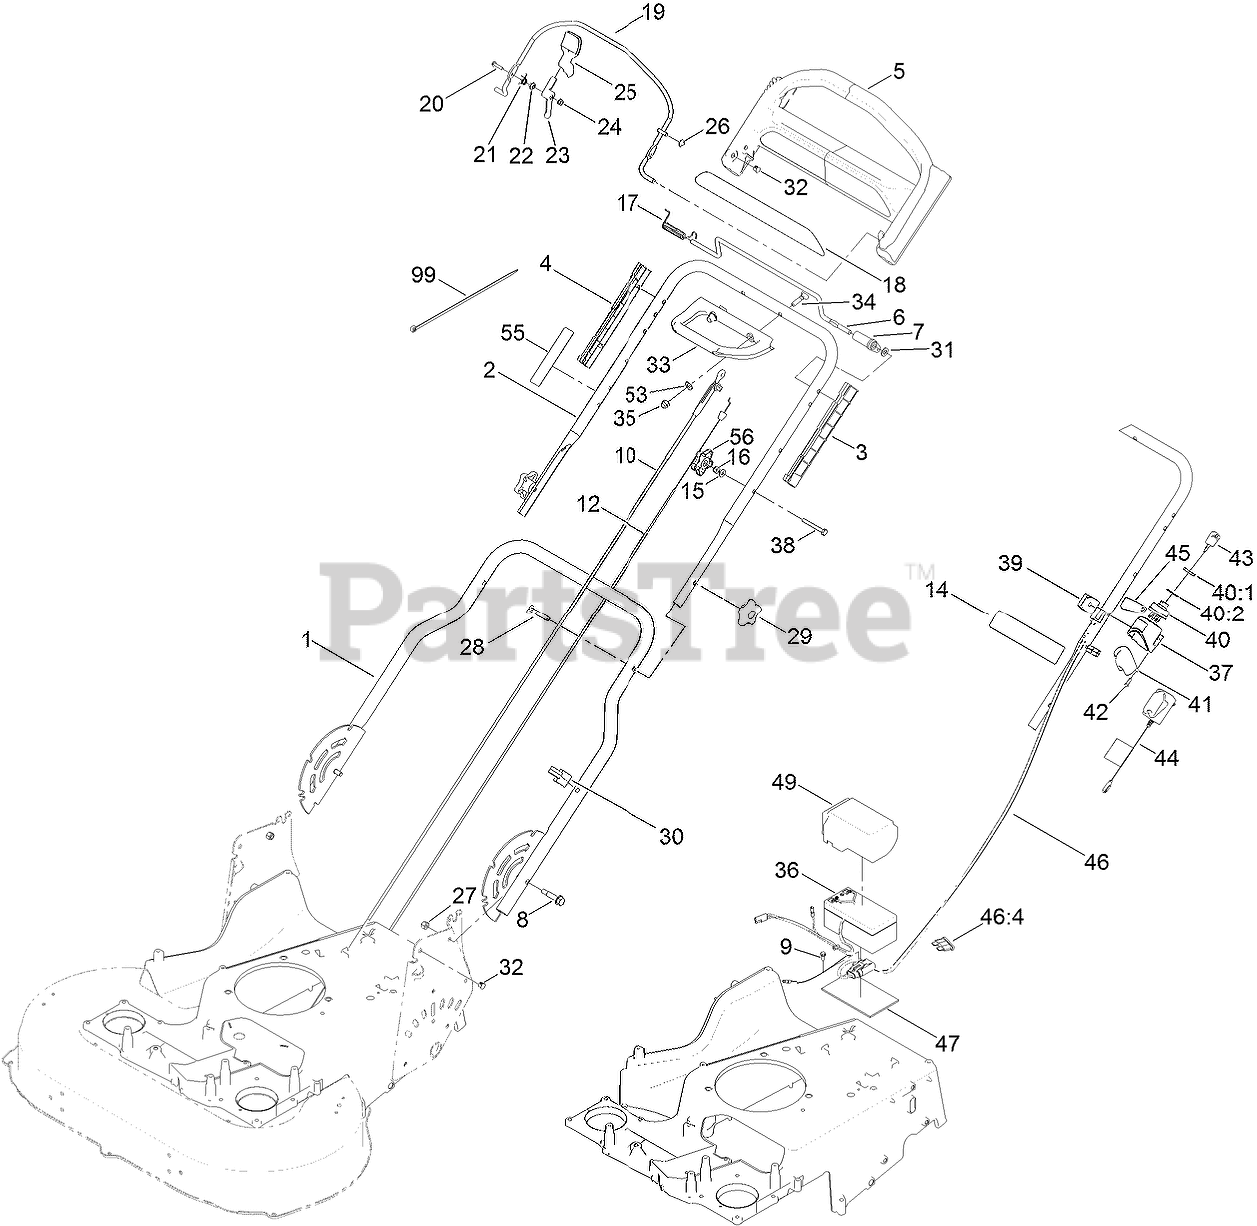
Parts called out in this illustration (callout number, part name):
1	HANDLE-LOWER
2	HANDLE-UPPER
3	GUIDE-LH
4	GUIDE-RH
5	HANDLE-CONTROL
6	BAR-CONTROL, TRACTION
7	LEVER-TRACTION
8	BOLT-SHOULDER, HHF
9	SCREW-TAPTITE
10	CABLE-BRAKE, BBC
12	CABLE-TRACTION
14	DECAL-WARNING
15	WASHER-FLAT
16	NUT-LOCK, NI
17	Spring-Torsion
18	DECAL-HANDLE
19	BAIL-BRAKE
20	SCREW-HWH
21	SPRING-TORSION
22	SPACER
23	LEVER
24	NUT-LOCK, FLANGE
26	NUT-SPEED
27	NUT-LOCK, NI
28	SCREW-HANDLE
29	KNOB-HANDLE
30	GUIDE-CABLE
31	SPACER
32	Plug-Dome
33	HANDLE-ASSIST, TRACTION
34	SCREW-HANDLE, LOCK
35	NUT-ACORN
36	BATTERY-WET
37	HOUSING-SWITCH, KEY
38	SCREW-HH
39	ANCHOR-CABLE, UPPER
40	SWITCH-STARTER
40:1	NUT-HH
40:2	WASHER-TOOTH, INTERNAL
41	COVER-SWTCH
42	SCREW-PPH
44	CHARGER-CE
45	DECAL-SWITCH, IGNITION
46	HARNESS-WIRE
46:4	FUSE-40 AMP
47	FOAM-BATTERY
49	COVER-BATTERY
53	WASHER-PLAIN
55	DECAL-TRACTION, ADJUST
56	KNOB-HANDLE, LOCKING
99	TIE-CABLE
